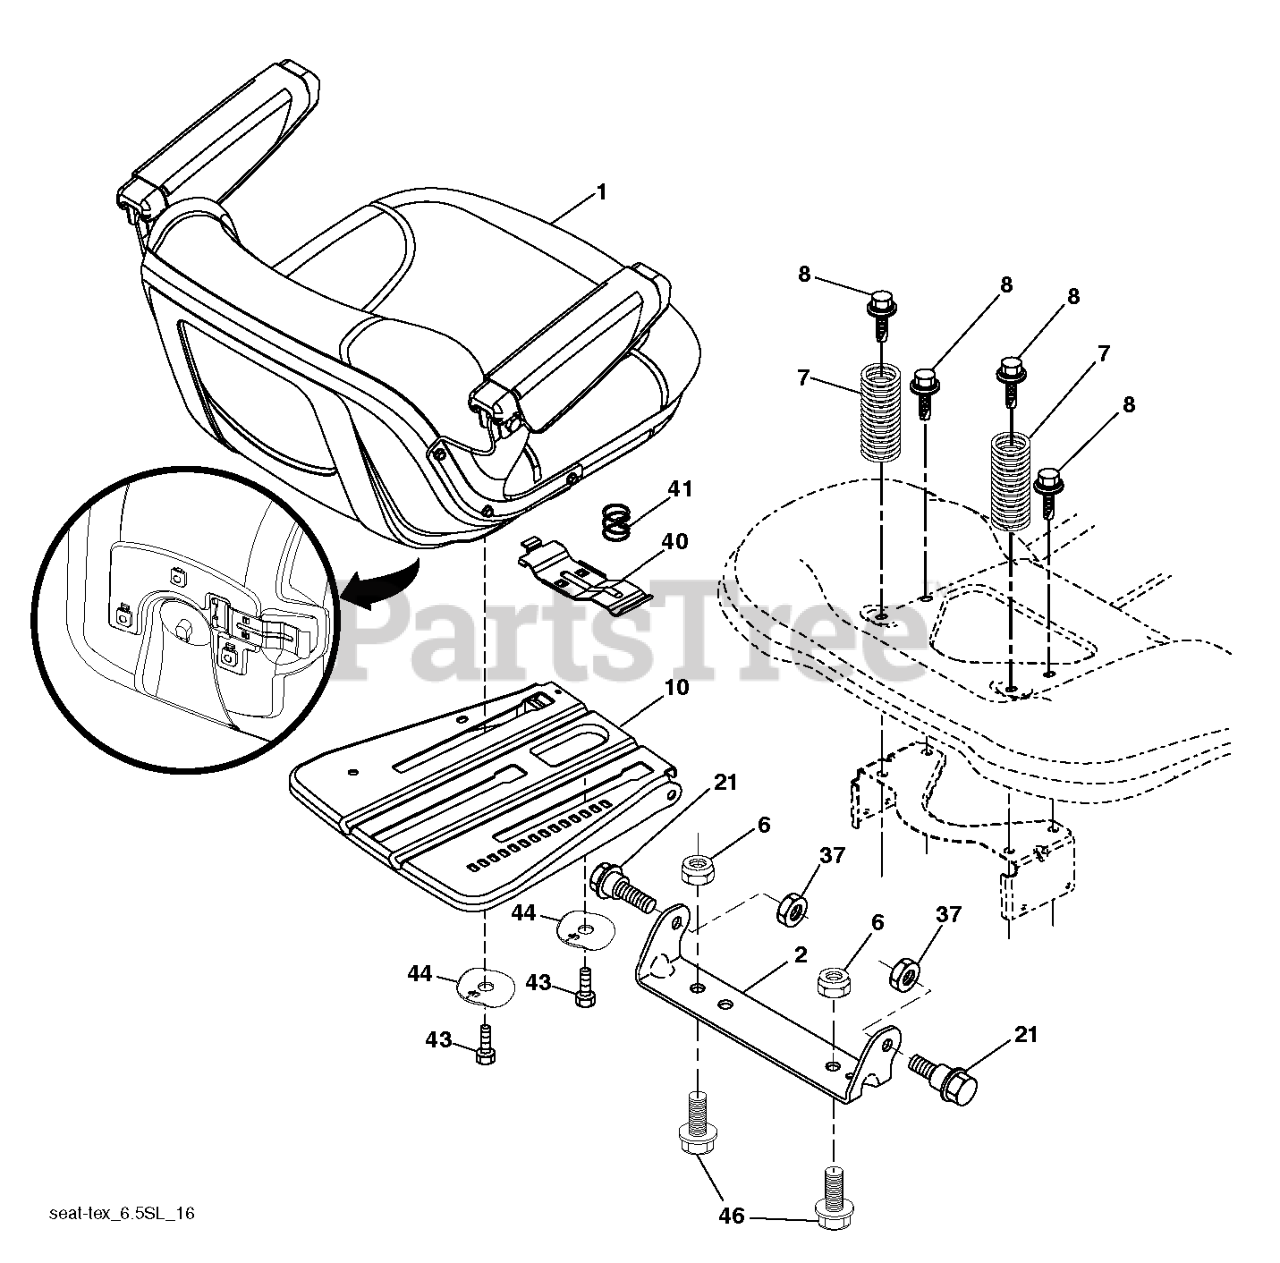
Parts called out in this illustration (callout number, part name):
1	SEAT.TH154.498GY.HUS.ARMRESTS
2	BRKT.PIVOT.FENDER
6	NUT
7	SPRING.COMPRESS.SEAT.TAPERED
8	BOLT.5/16-18UNCX3/4 W/SEMS.BLK
10	PLATE SEAT; SLIDE; 3PT BLACK;
21	BOLT.5/16-18X5/8.SHOULDER
37	NUT.71038.31-18.HEX.NYLOCK
40	HANDLE.SLIDE.SEAT.TEX.BLACK
41	SPRING.LATCH.SEAT.TEX
44	WASHER.WINGED.3/8ID.1.5OD
46	BOLT.3/8-16X1;1.25OD.WSHR.SEMS
